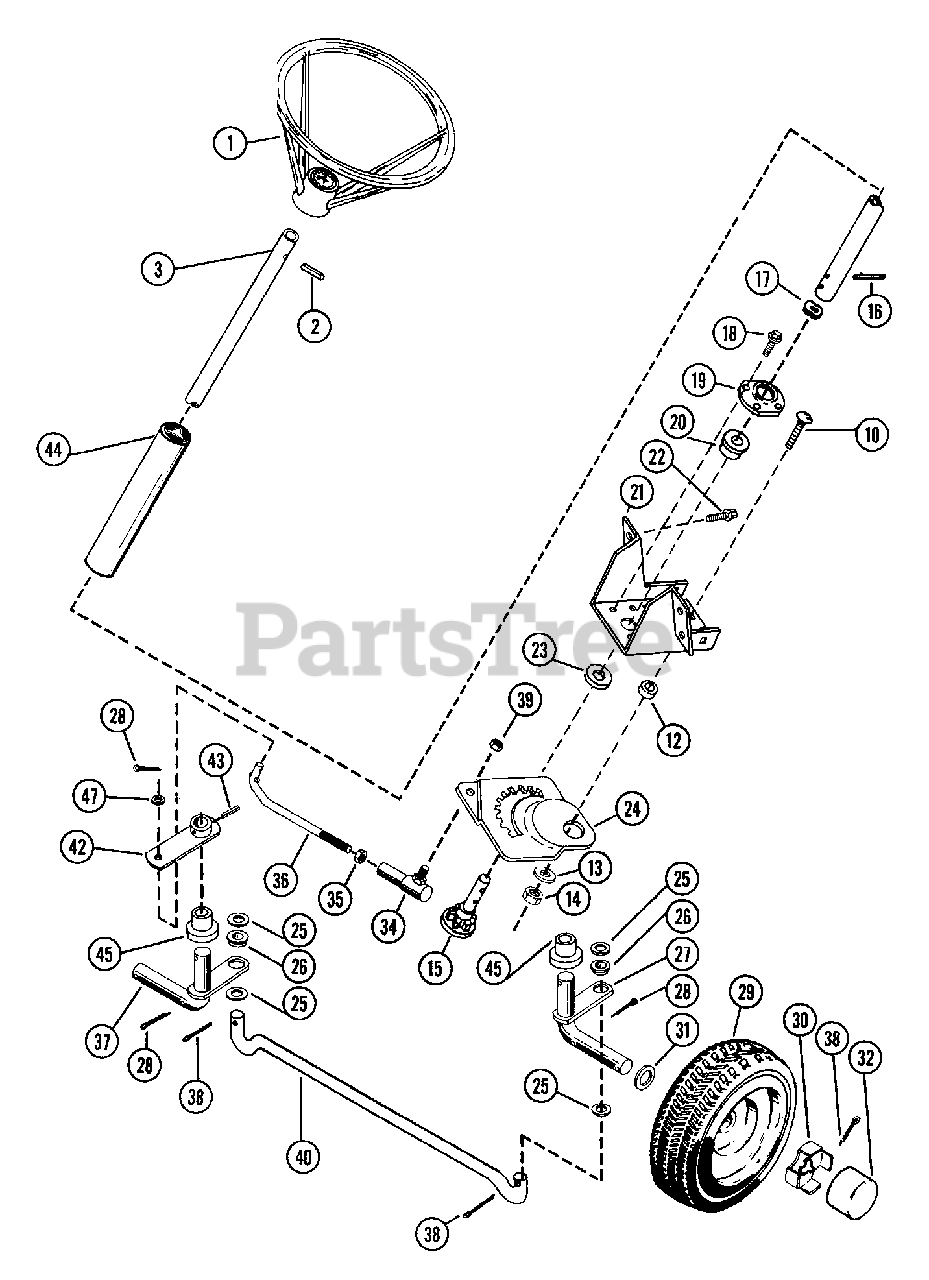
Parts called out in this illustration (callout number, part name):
1	STEERING WHEEL
2	PIN-ROLL .250X1.75
3	STEERING SHAFT
10	BLT-RDHDSQSHNK .38-16X1.00 PL
12	SPACER .380X.750X.236
13	WSHR-FL-STL .390X1.500X.125
14	NUT-LK-JAM-CTR .375-16 PL
15	PINION
16	PIN-ROLL .188X1.00
17	WAVE WASHER .531X.781X.125FH
18	SCR-TAP 10-24X.25 CRSLPH PL 1A
19	RETAINING PLATE
20	BSHG-FLG .625X1.156X.375 SI
21	STEERING BRACKET
22	BLT-SERHFWH .31-18X.50 PL
23	WSHR-FL-STL .630X1.250X.062 PL
24	STEERING GEAR
25	WSHR-FL-STL .505X.875X.024 PL
26	BSHG-FLG.500X.625X.312X.750NY
27	L.H. WHEEL SPINDLE
28	PIN-COTR .12 X 1.25 PL
29	FRONT WHEEL ASSEMBLY
29	TIRE 4.10/3.50-4
29	WHL
29	ZERK FITTING
29	BSHG-FLG .750X1.380X.750X1.557
30	SPINDLE CUP
31	SPINDLE WASHER
32	HUB CAP
34	BALL JOINT
35	NUT .375-24 PL
36	WIRE HARNESS
37	R.H. WHEEL SPINDLE
38	PIN-COTR .12X1.0 PL
39	NUT-LK .375-24 PL
40	TIE ROD
43	PIN-GRV .250X1.25 TP A
45	FLANGE BUSHING
47	WSHR-FL-STL .755X1.375X.062 PL
